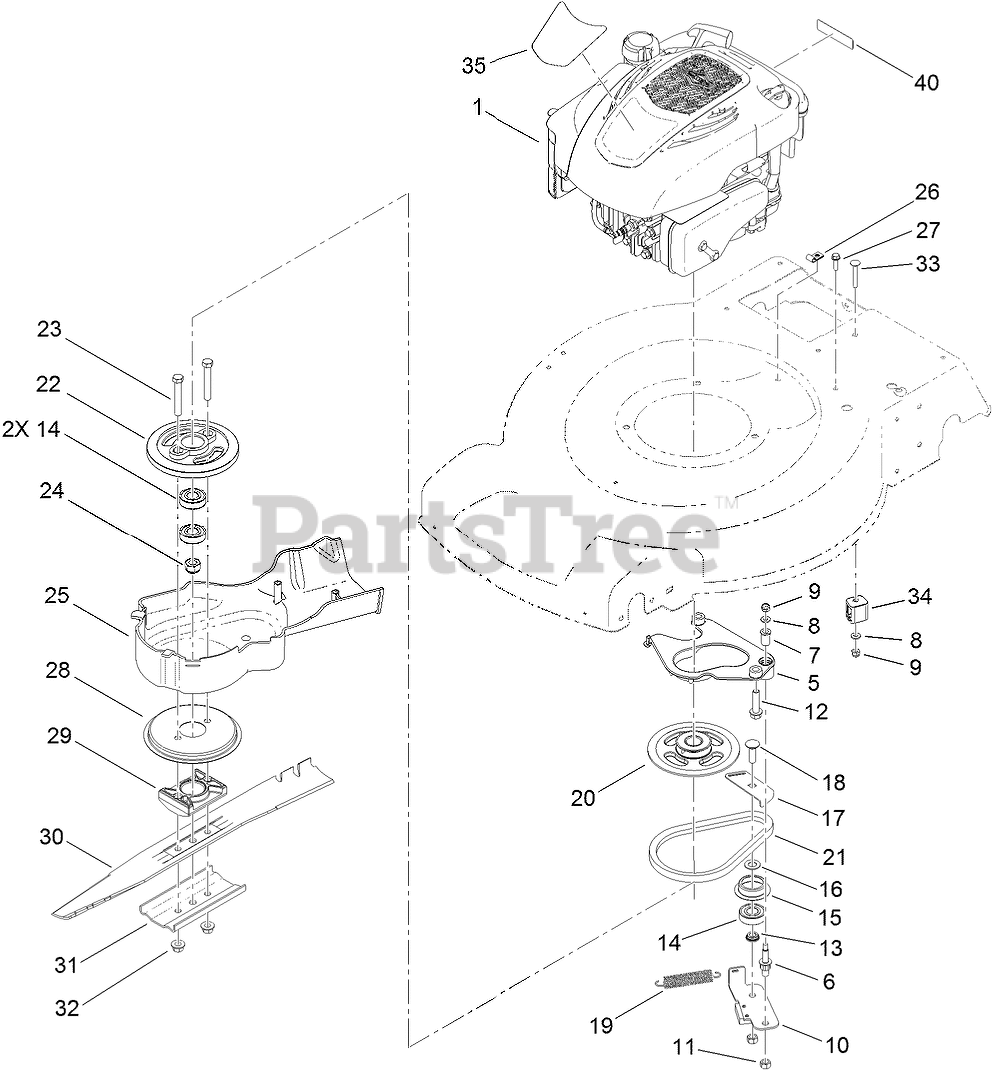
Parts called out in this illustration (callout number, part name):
5	PLATE-ANCHOR
6	BOLT-SHOULDER
7	BUSHING
8	WASHER-FLAT
9	NUT-LOCK, NI
10	BRAKE ARM ASM
12	SCREW-HWH
13	SPACER-BEARING
14	BEARING-BALL
15	RETAINER-BELT
16	WASHER-PLAIN
17	PLATE-GUIDE
18	BOLT-CARR
19	SPRING-TENSION, BRAKE
20	PULLEY
21	BELT
22	DRUM
23	SCREW-HH
24	NUT-HEX
26	CLIP-CLOSED, INSULATED
27	SCREW-HWH
28	DISC
29	SUPPORT-BLADE
30	BLADE-22 INCH
31	SUPPORT-BLADE
32	NUT-LOCK
33	SCREW-CARR
34	ANCHOR-CABLE
35	DECAL-SHROUD
40	DECAL-ARRESTER, SPARK
